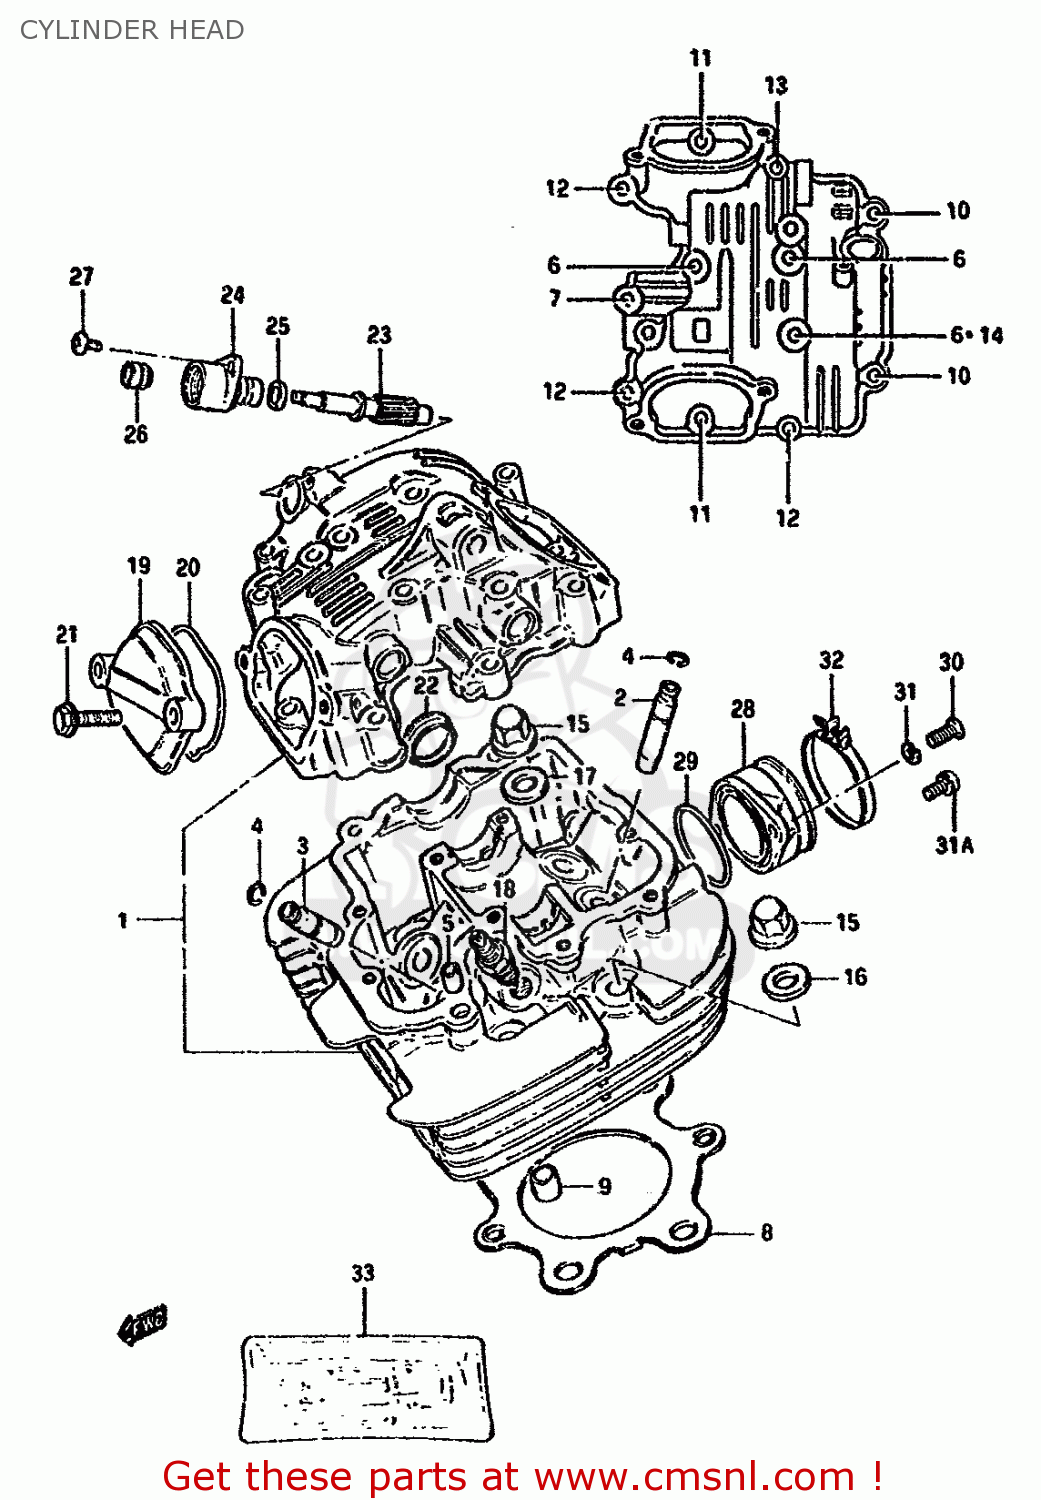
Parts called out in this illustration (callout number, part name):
1	HEAD,CYLINDER
2	GUIDE,INTAKE VALVE
3	GUIDE,VALVE
4	RING,SNAP
5	PIN(6.2X8X11)
6	BOLT
7	BOLT
8	GASKET,CYLINDER HEAD (NAS)
9	PIN
10	BOLT(6X115)
11	BOLT
12	BOLT
13	BOLT
14	GASKET(5.8X13X1.2) (NAS)
15	NUT
16	WASHER(10.5X22X2.3)
17	GASKET(10.5X22X2) (NAS)
18	SPARK PLUG D8EA
19	CAP,INSPECTION
20	O RING(D:2.4,ID:23)
21	BOLT
22	PLUG(OD:30)
23	GEAR,TACHOMETER DRIVEN
24	SLEEVE,TACHOMETER DRIVE GEAR
25	SEAL,TACHOMETER DRIVEN
26	SEAL,OIL(5X12X8)
27	SCREW(5X12)
28	PIPE,INTAKE
29	O-RING (D:2.4 ID:39.7)
30	SCREW
31	WASHER,LOCK
31A	SCREW
32	CLAMP
33	GASKET SET
